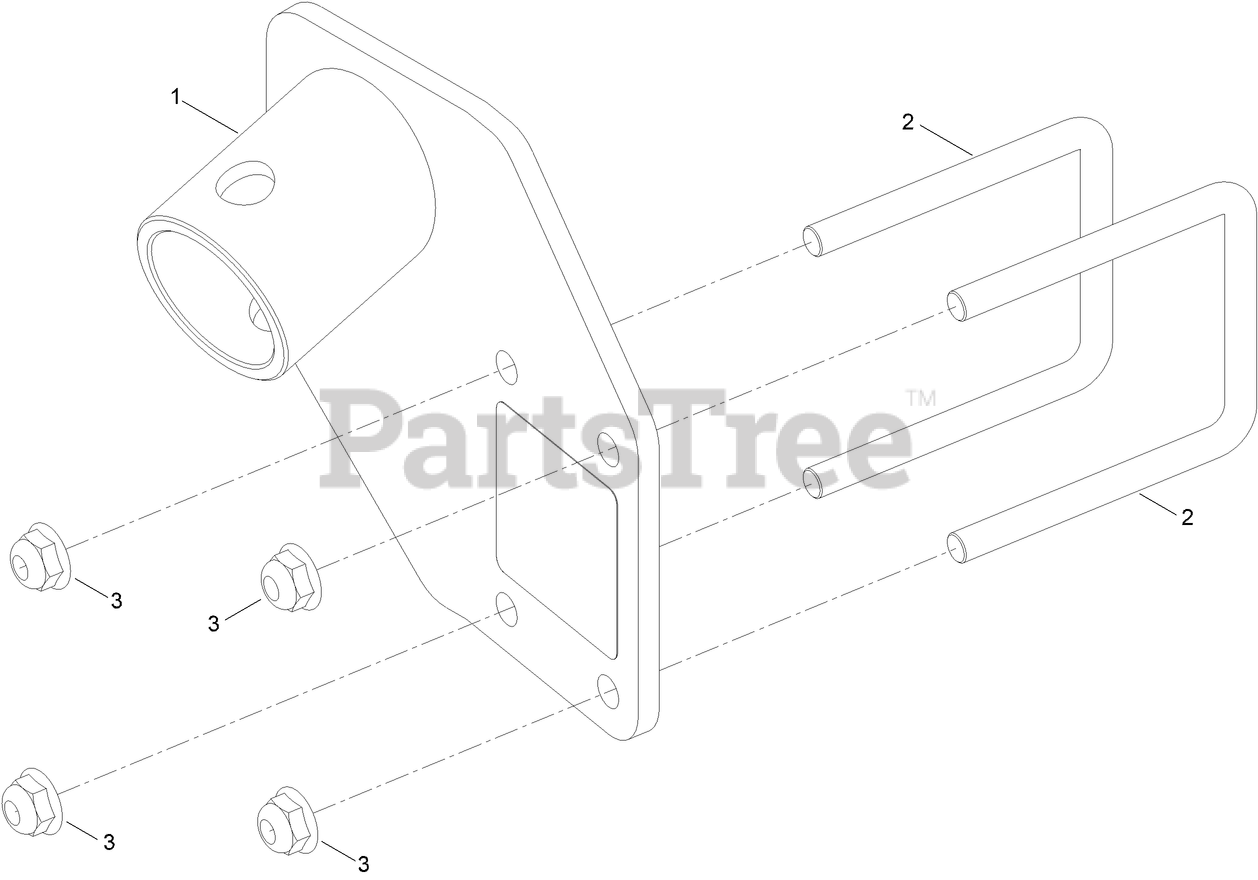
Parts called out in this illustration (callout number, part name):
1	MOUNT, JACK W/ DECAL
2	U-BOLT
3	NUT-HF
